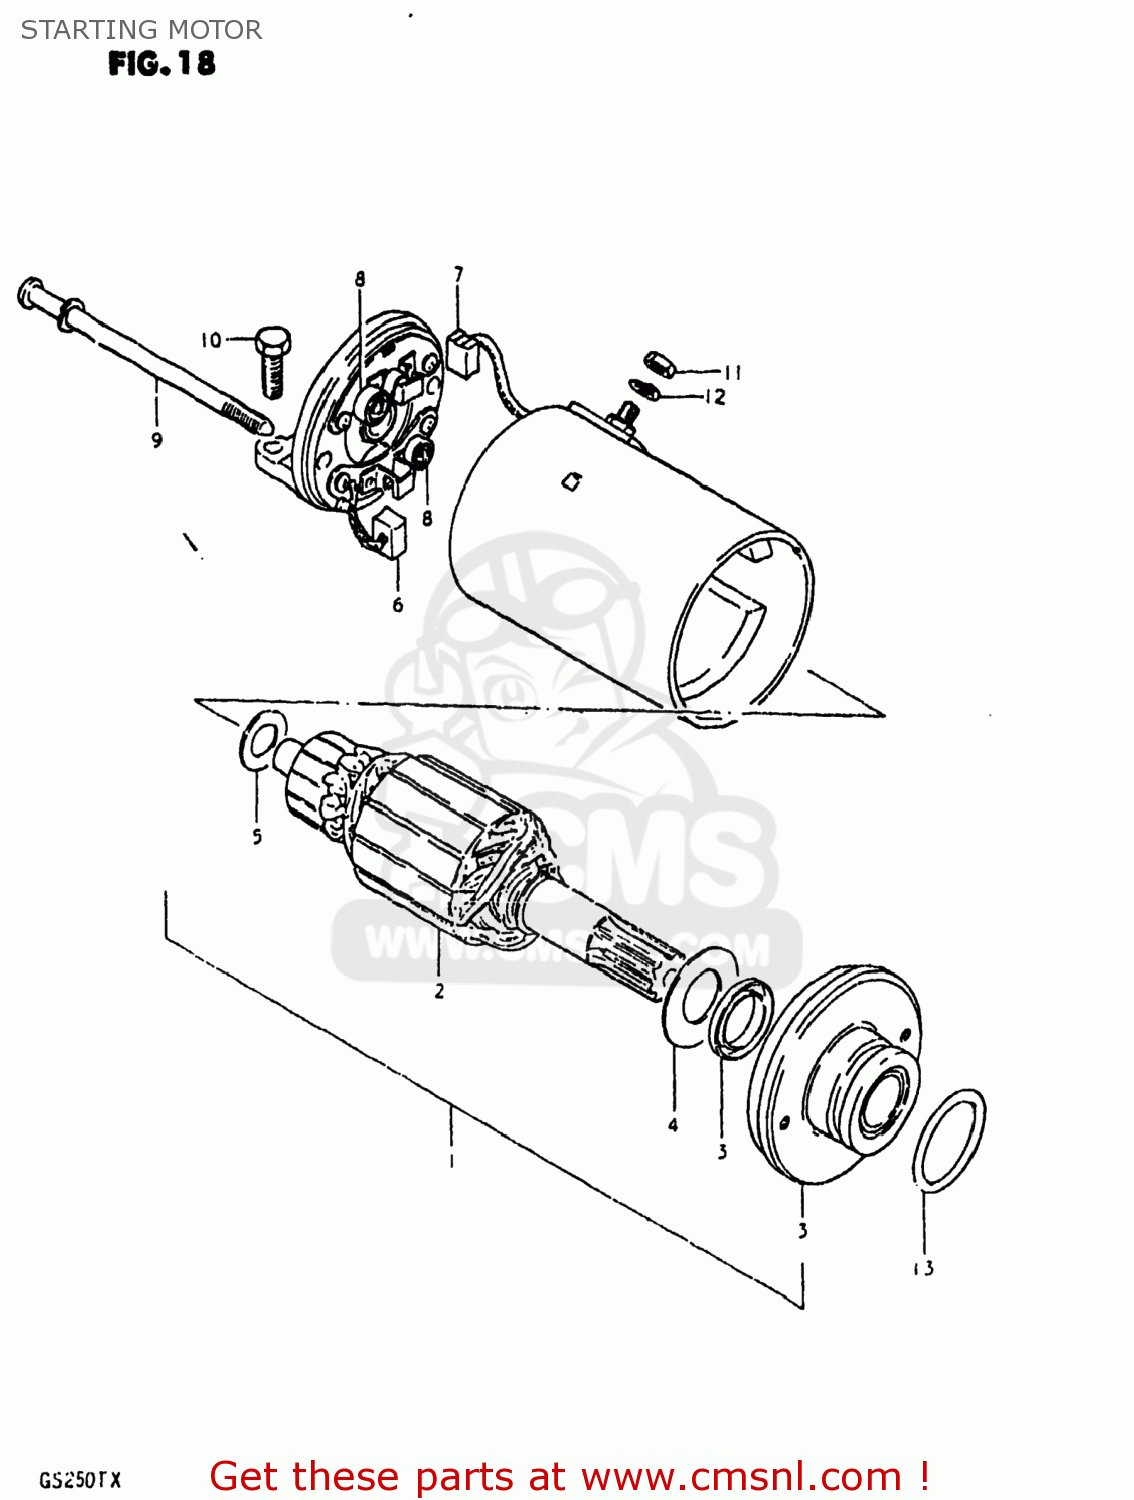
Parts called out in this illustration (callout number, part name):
1	MOTOR ASSEMBLY,STARTING
2	ARMATURE
3	SEAL,OIL
4	RING,SNAP
5	SHIM,ARMATURE
6	BRUSH(-)
7	BRUSH TERMINAL SET
8	SPRING
9	BOLT,STARTING MOTOR HOUSING
10	BOLT, UPPER
11	NUT 6MM
12	LOCK WASHER
13	O RING(D:2,ID:24.5)
